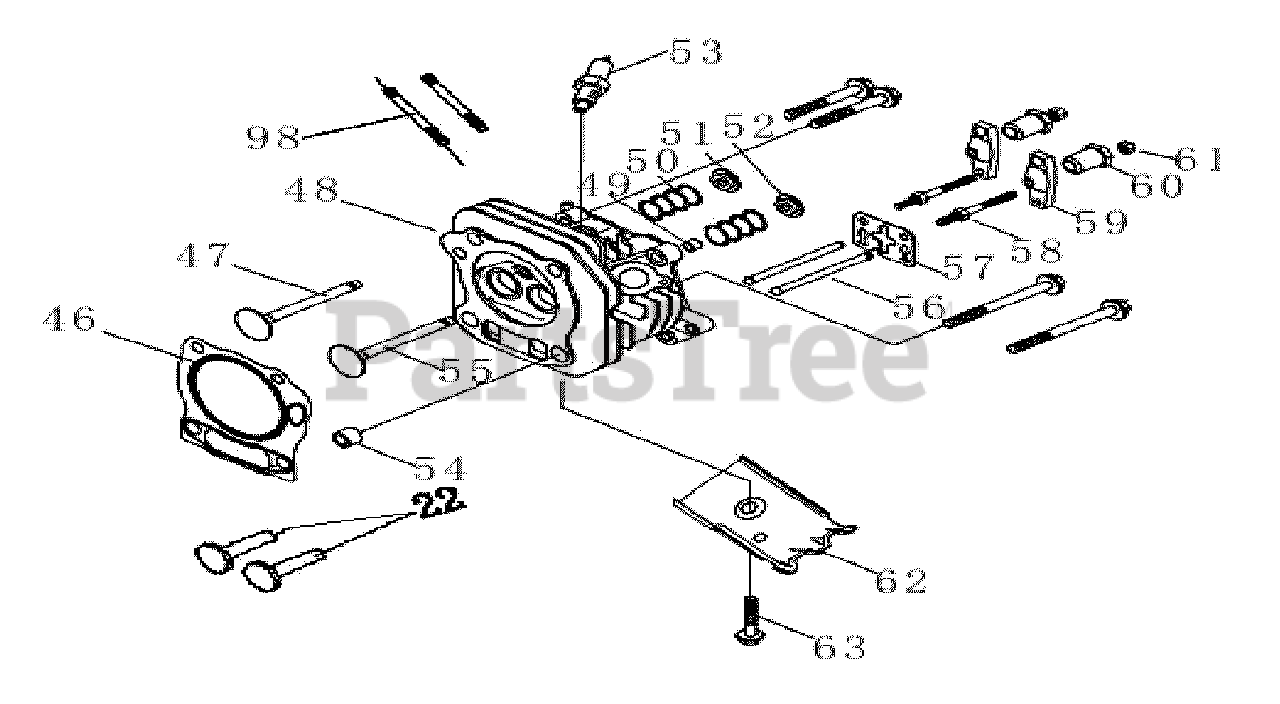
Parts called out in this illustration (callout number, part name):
22	Valve lifter
47	Intake valve
48	Cylinder head
49	Exhaust valve bushing
50	Valve spring
51	Intake valve retainer
52	Exhaust valve retainer
53	Spark plug
54	Locating ring
55	Exhaust valve
56	Push rod
57	Push rod guide
58	Rocker screw
59	Valve rocker arm
60	Adjuster
61	M6 x 0.75 nut
62	Wind guide
63	M6 x 12 flanged bolt
